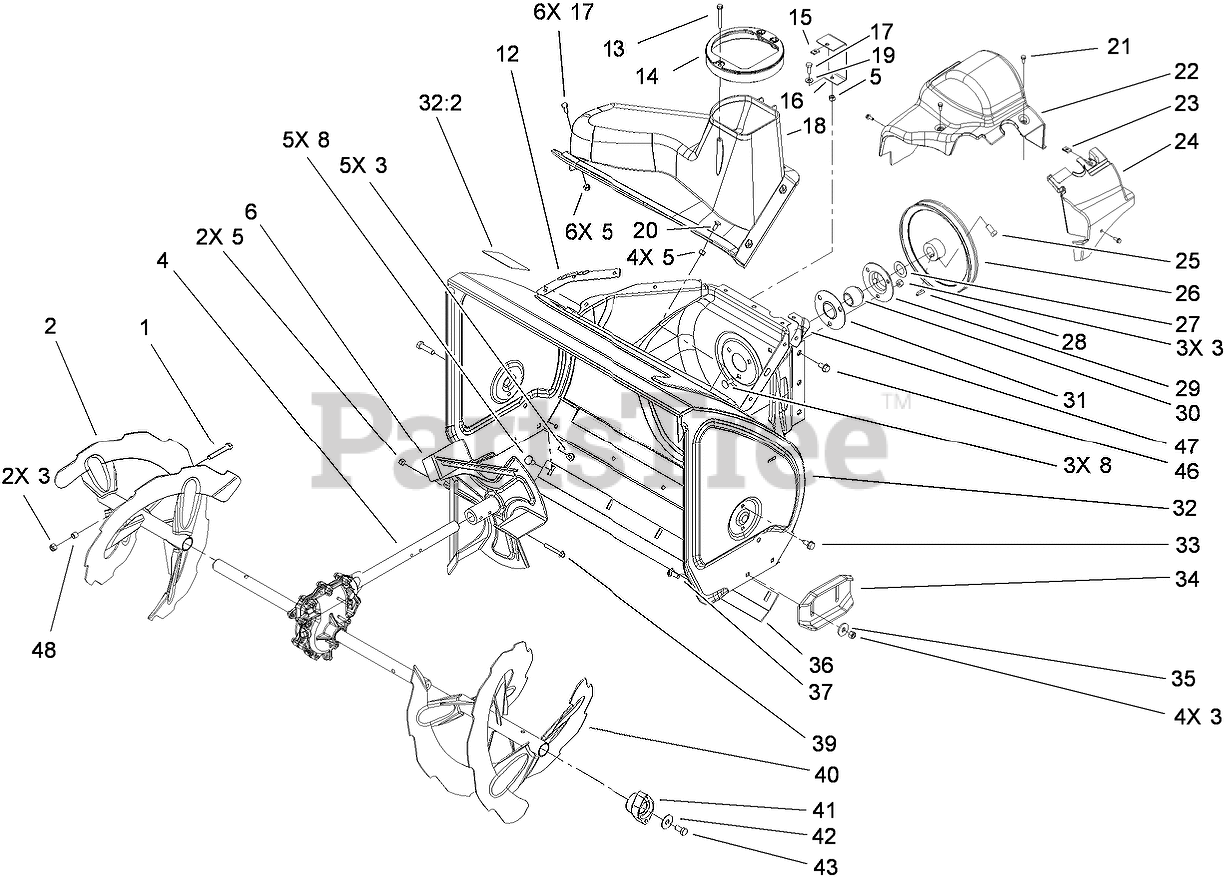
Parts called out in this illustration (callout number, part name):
1	SCREW-HH
2	RH AUGER ASM
3	NUT-LOCK, NI
4	26 INCH AUGER GEARCASE ASM
5	NUT-LOCK, NI
6	IMPELLER ASM
8	SCREW-CARR
12	SEAL-FLANGE, COVER
13	SCREW-PLASTITE
14	GUIDE-CHUTE
15	NUT-SPEED, U-TYPE
16	BRACKET-COVER, CLIP NUT
17	SCREW-HH
19	WASHER-FLAT
20	BOLT-CARR
21	SCREW-HWH
22	COVER-BELT
23	NUT-SPEED
24	COVER-EXTENSION, BELT
25	SCREW-SET, SQH
26	PULLEY-IMPELLER
27	WASHER-THRUST
28	KEY-WOODRUFF
29	FLANGE-CUP, BEARING
30	BEARING-BALL
31	FLANGE-CUP, BEARING
32	HOUSING-AUGER, 26 INCH
32:2	DECAL-WARNING, AUGER
33	SCREW-HWHTF
35	WASHER
36	SCRAPER-FIXED
37	SCREW-CARR
39	SCREW-HHF
40	LH AUGER ASM
41	BEARING-AUGER
42	WASHER
43	SCREW-HH
46	SCREW-HWHTF
48	SPACER
